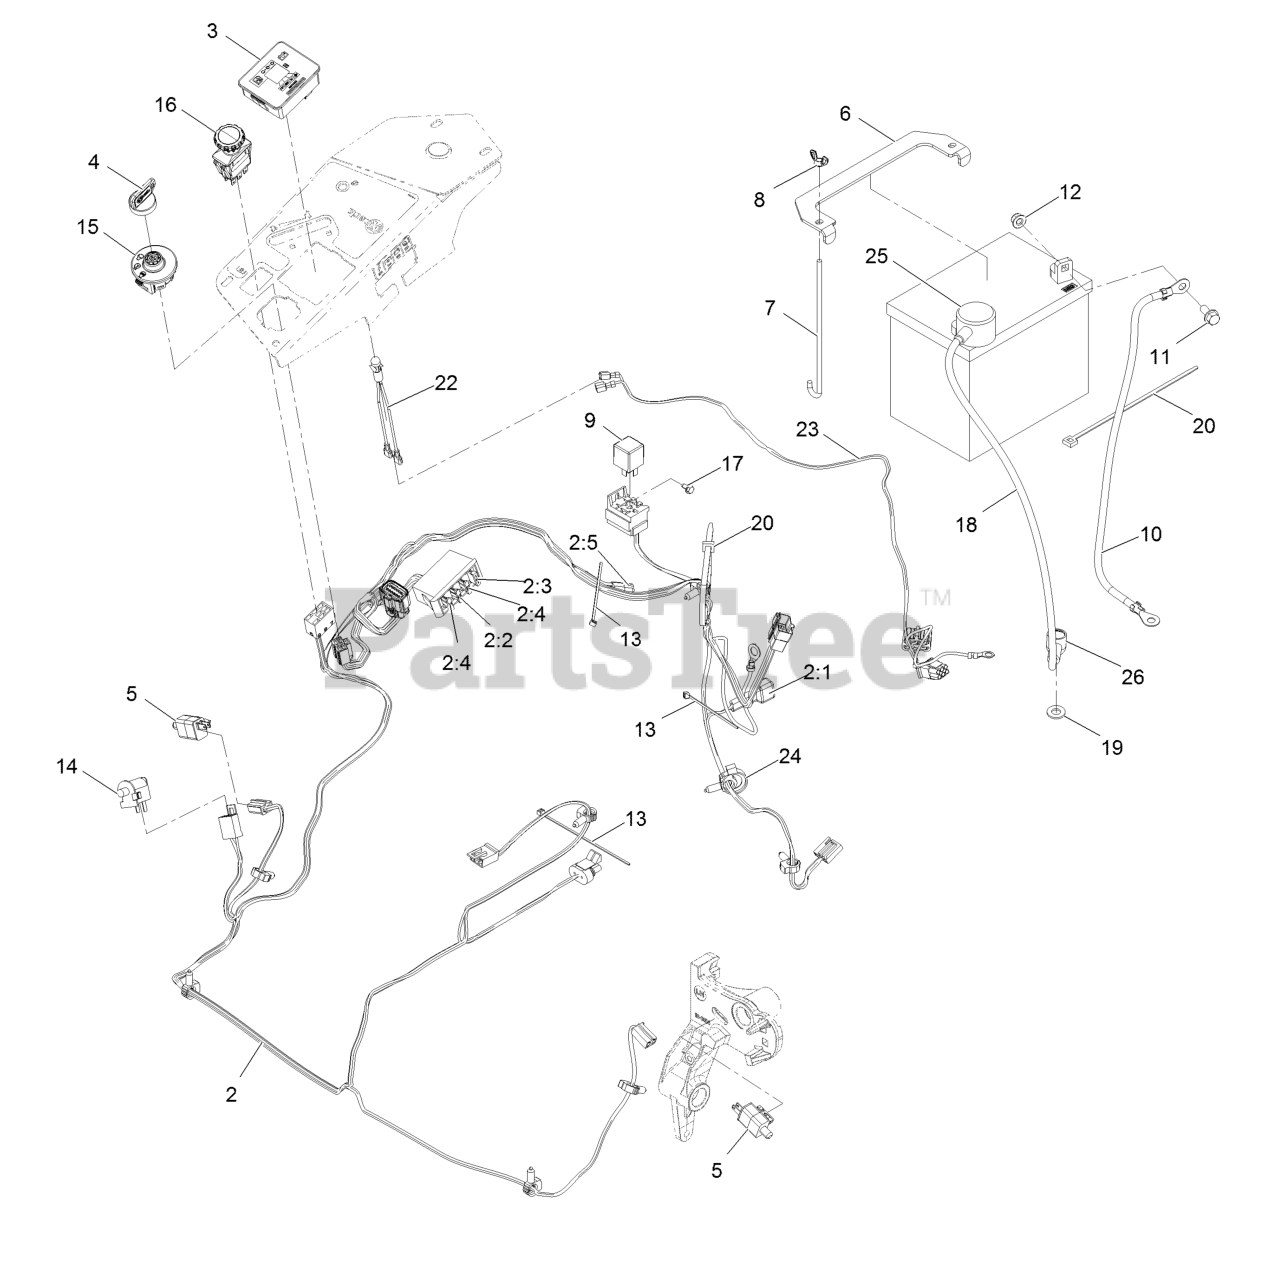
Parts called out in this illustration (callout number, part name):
2	Harness-Wire, Main
2:2	Fuse-Blade, 10 Amp
2:3	Fuse-Blade, 15 Amp
2:4	Fuse-Blade, 25 Amp
2:5	Cap-Plug
3	Fuel/Hour Meter ASM
4	Key-Ignition
4	Key-Exmark Logo
6	Strap-Tie Down, Battery
7	Bolt-Holddown
8	Wingnut-Nyloc 1/4-20
9	Relay-12Vdc 40 Amp
10	Cable-Battery, Negative
11	Screw-HH Flg 5/16-18 X 3/4
12	Nut-Nyloc 5/16-18 Flg
13	Tie-Cable 5 1/2 (Small)
15	Switch-Ignition
16	Switch-PTO, 10 Amp
17	Screw-HWH #10-24 X 3/8
18	Cable-Battery, Positive
19	Washer-3/8 SAE
20	Tie-Cable 7 15/16 (Large)
22	Indicator-Red LED
23	Harness-Light, Indicator
24	Clamp-Hose
25	Insulator-Battery
26	Insulator-Solenoid
